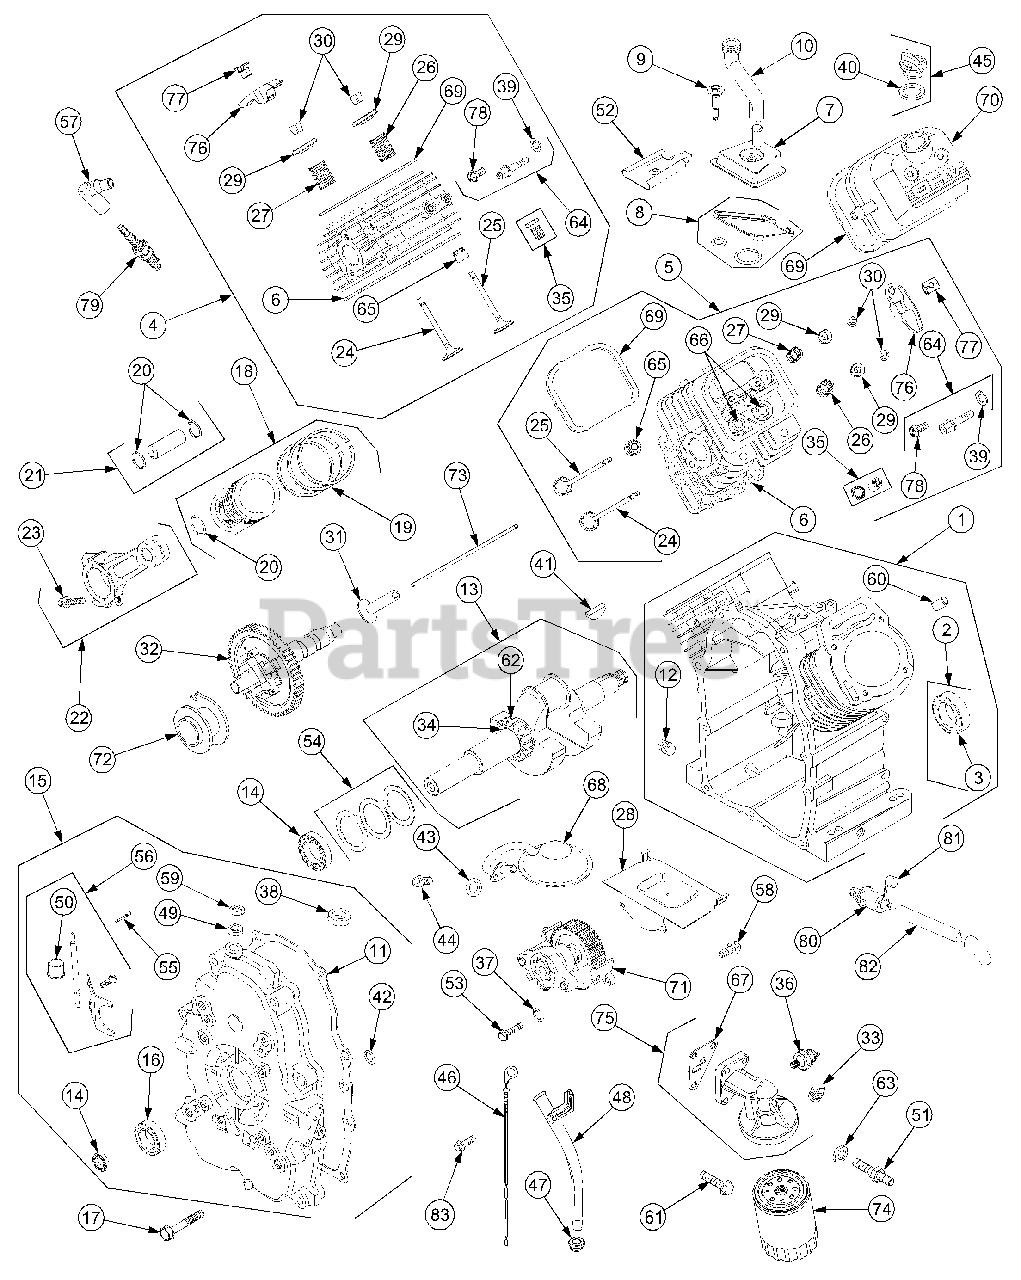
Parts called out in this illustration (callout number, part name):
1	Cylinder Assembly
2	Kit, Bushing/Seal (Magneto Side)
3	Seal, Oil
4	Head, Cylinder (#1)
5	Head, Cylinder (#2)
6	Gasket, Cylinder Head
7	Breather Assembly
8	Gasket, Breather
9	Screw (Breather Ass'y.)
10	Tube, Breather
11	Gasket, Crankcase
12	Plug, Oil Drain
13	Crankshaft
14	Bearing, Ball
15	Cover, Crankcase
16	Seal, Oil (PTO Side)
17	Screw (Crankcase Cover)
18	Piston Assembly
19	Ring Set
20	Lock, Piston Pin
21	Pin, Piston
22	Rod, Connecting
23	Screw, Connecting Rod
24	Valve, Exhaust
25	Valve, Intake
26	Spring, Valve (Intake)
27	Spring, Valve (Exhaust)
29	Retainer, Valve
30	Keeper, Valve
31	Tappet, Valve
32	Camshaft
33	Plug, Oil
34	Key, Timing
35	Adjuster, Rocker Arm
36	Switch, Oil Pressure
37	Seal, Oil Ring (Oil Pump)
38	Washer, Sealing
39	Washer, Sealing
40	Gasket, Oil Fill
41	Key, Woodruff
42	Seal, O-Ring
43	Seal, O-Ring
44	Screw
45	Plug, Oil Fill
47	Seal, Dipstick Tube
48	Tube, Dipstick
49	Bushing, Governor Shaft
50	Bushing, Governor Shaft
51	Stud, Oil Filter Adapter
52	Baffle, Breather
54	Shim, End Play
55	Retainer, Governor Shaft
56	Shaft, Governor
57	Boot, Spark Plug
59	Seal, Governor Shaft
60	Pin, Locating
62	Gear, Timing
64	Stud, Rocker Arm
65	Seal, Valve
67	Gasket, Oil Adapter
68	Screen, Oil Pump
69	Gasket, Rocker Cover
70	Cover, Rocker Arm
72	Spool, Governor
73	Rod, Push (Steel)
74	Filter, Oil
75	Adapter, Oil Filter
76	Arm, Rocker
77	Pivot, Rocker Arm
78	Screw, Rocker Cover
79	Screw, Sems
80	Drain, Oil
82	Hose, Oil Drain
83	Screw, Dipstick Tube
